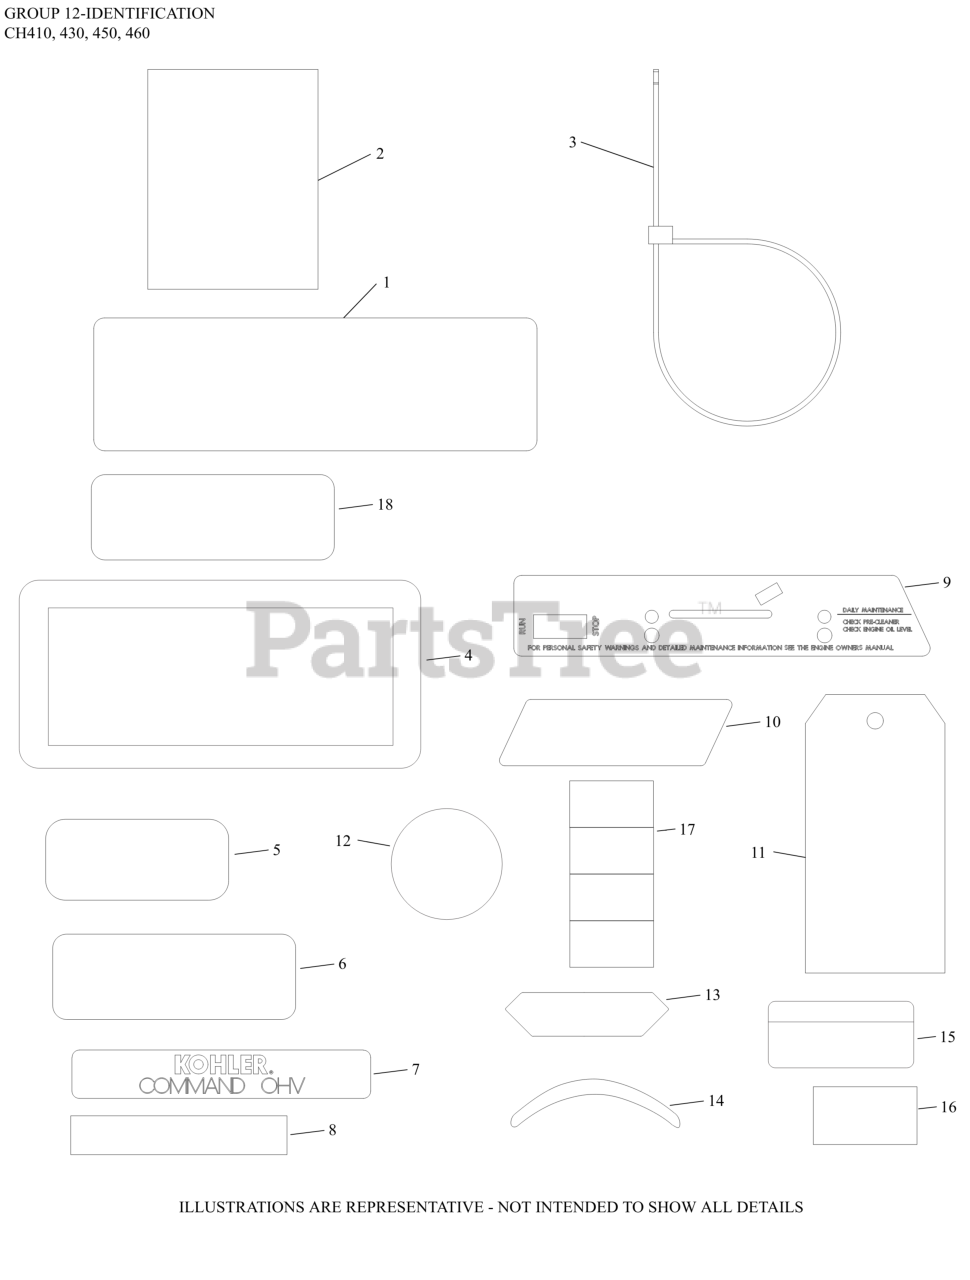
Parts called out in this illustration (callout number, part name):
1	DECAL , 13 HP
2	DECAL, CLEAR LAMINATE-(#2511370S)
5	DECAL, CHOKE (WHITE)
11	TAG, HANG - DISCONTINUED
12	LABEL, (ROUND KOHLER GOLD)-USE 24 113 18
13	DECAL, OIL SENTRY - DISCONTINUED
